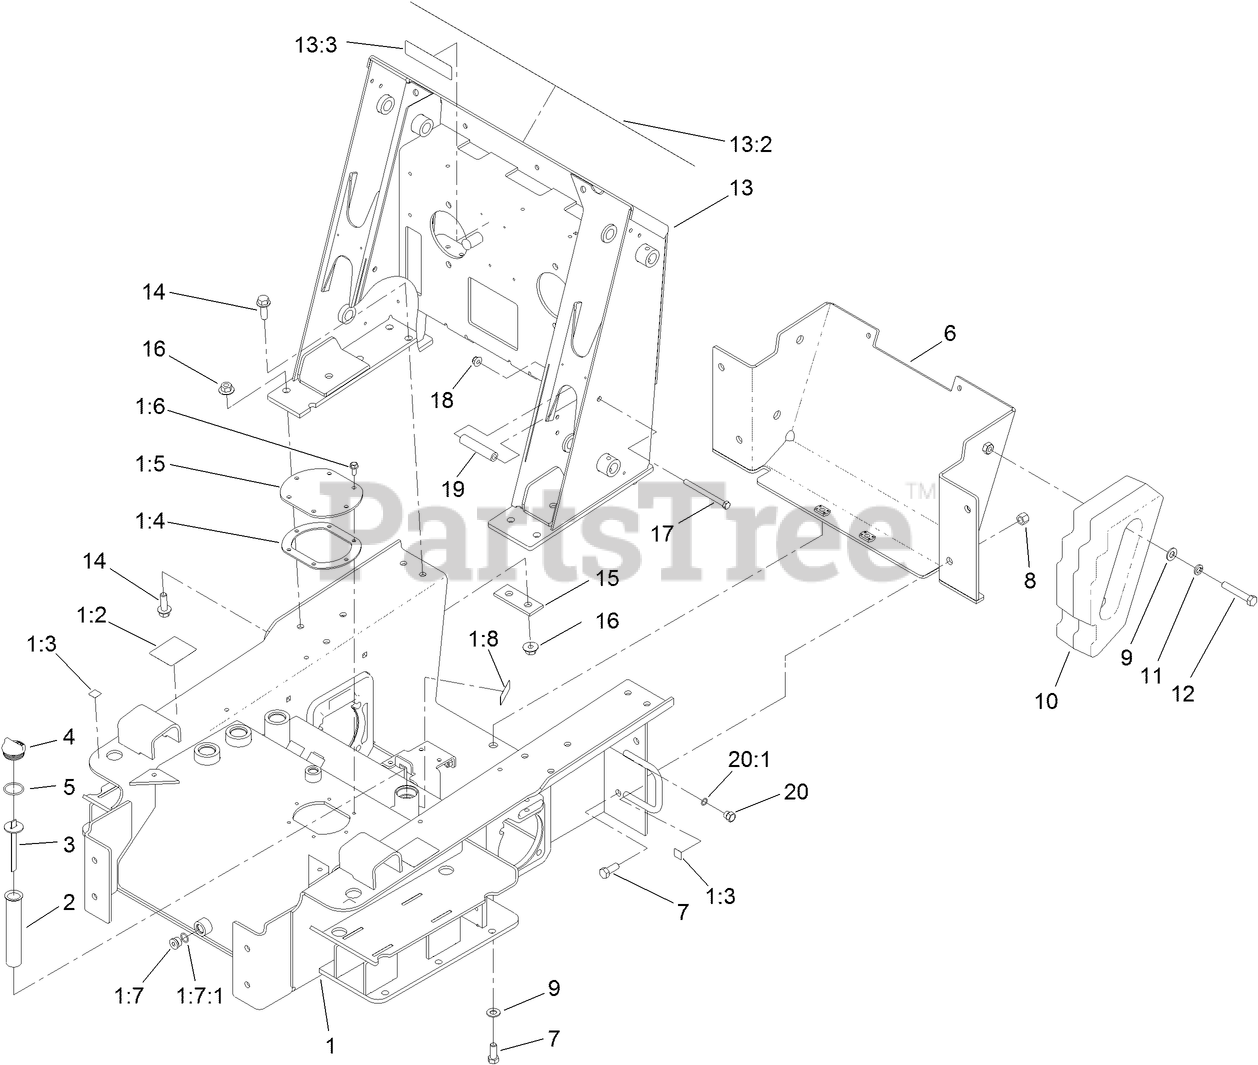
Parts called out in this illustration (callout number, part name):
1	CHASSIS ASM
1:2	DECAL-WARNING
1:3	DECAL-POINT, LIFT
1:4	GASKET-COVER, ACCESS
1:5	COVER-TANK
1:6	SCREW-HHF
1:7	PLUG-HEX
1:7:1	O-RING
1:8	DECAL-OIL, HYD
2	FILTER-SCREEN
3	DIPSTICK-OIL
4	PLUG-PLASTIC
5	O-RING
6	COVER-REAR
7	SCREW-HH
8	NUT-LOCK, NI
9	WASHER-FLAT
10	COUNTERWEIGHT-REAR
11	WASHER-LOCK
12	SCREW-HH
13	LOADER TOWER ASM
13:2	DECAL-PANEL, CONTROL
13:3	DECAL-DANGER
14	SCREW-HHF
15	PLATE-STIFFENER
16	NUT-LOCK, FLANGE
17	SCREW-HH
18	NUT-HF, NI
19	TUBE-SPACER
20	PLUG-HH
20:1	O-RING
